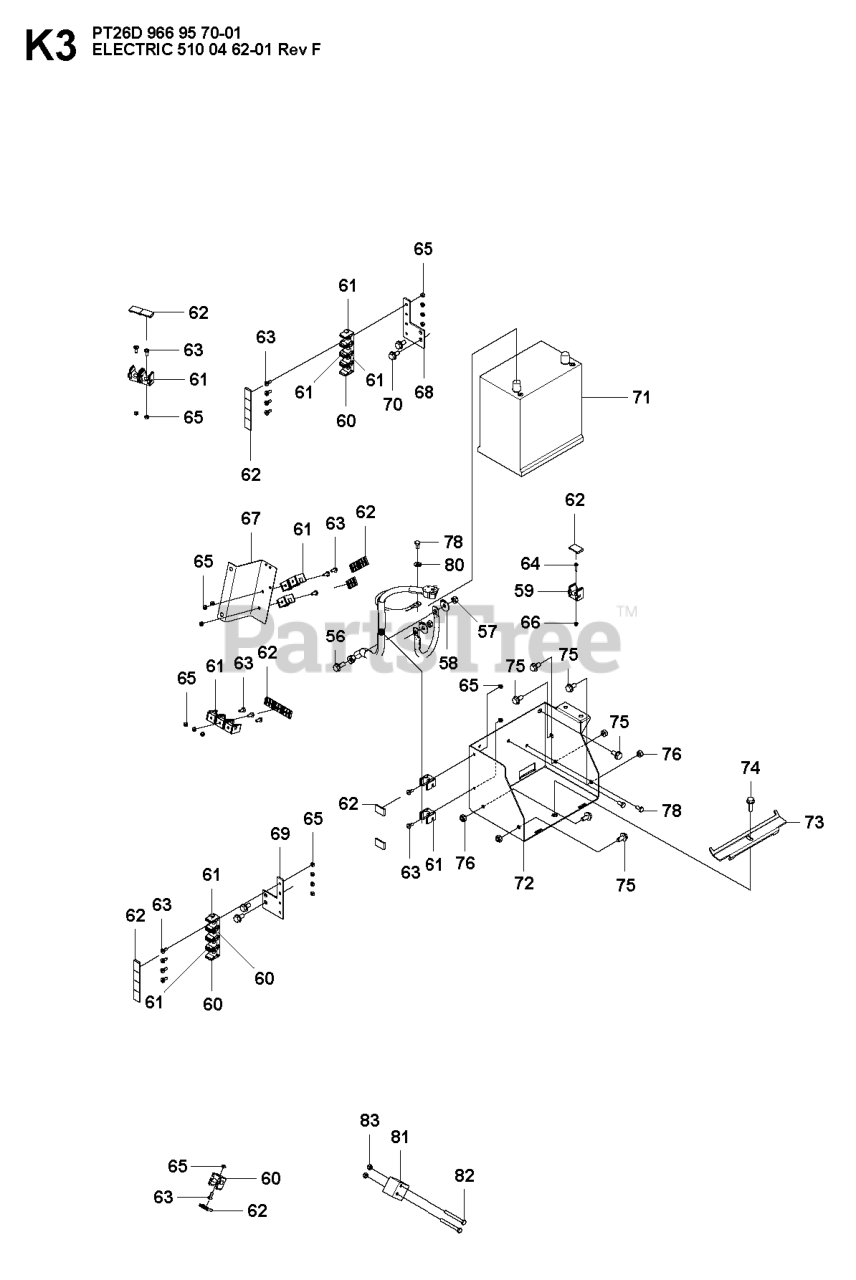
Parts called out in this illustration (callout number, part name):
57	LOCKNUT M8
58	WASHER BRB 8.4X17
65	LOCKNUT M5
74	BOLT
76	LOCKNUT M8
80	WASHER
81	BRACKET SENSOR LIFT
82	SCREW M6X55
83	LOCKNUT M6
